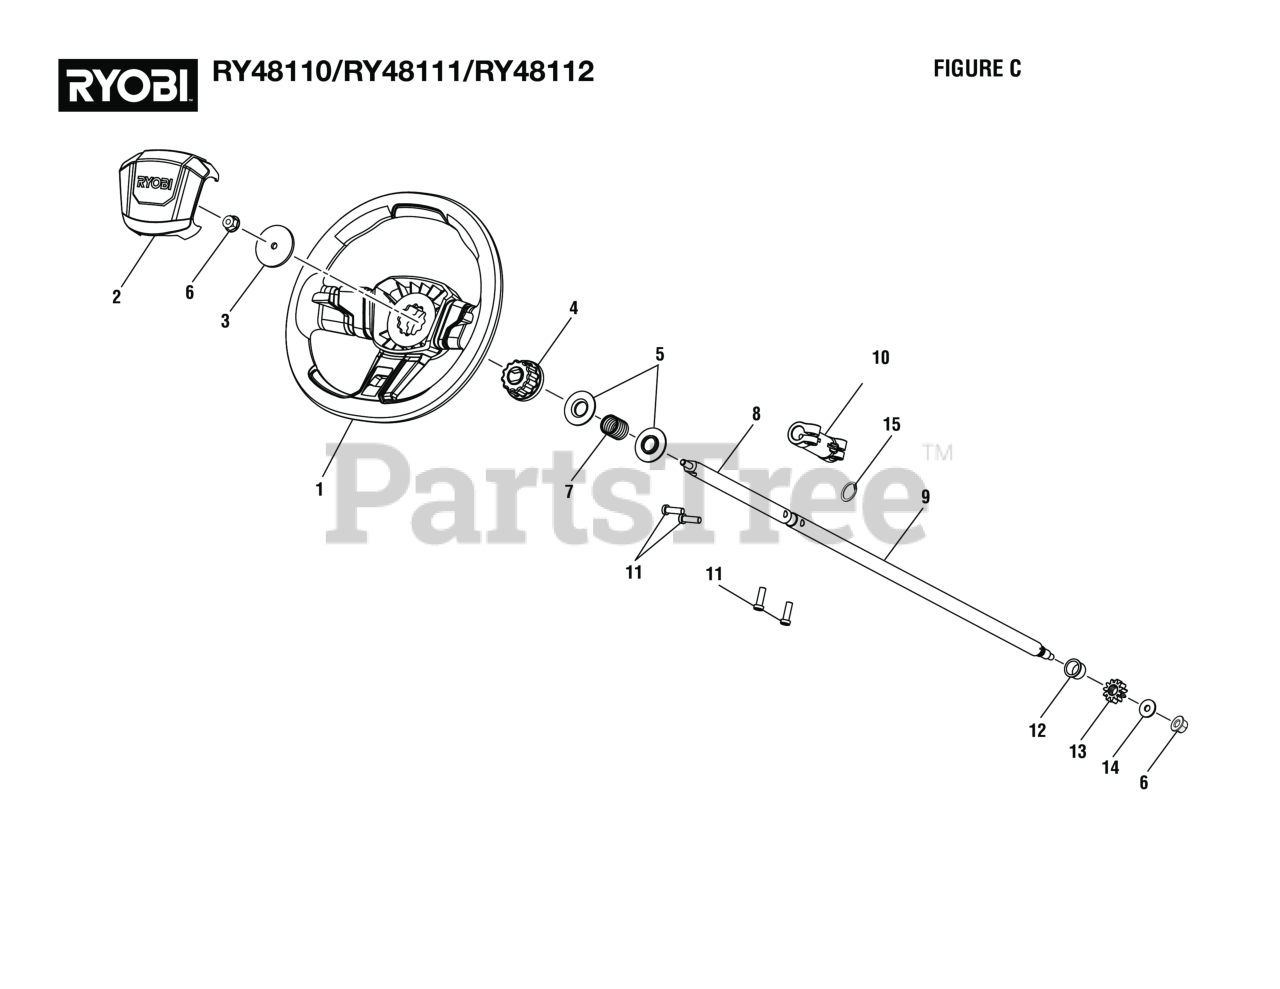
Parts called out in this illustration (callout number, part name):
1	Steering Wheel
2	Steering Wheel Cap
3	Washer Plate
4	Spline Collar
5	Spring Seat
6	Flange Nut (M8) (For Drive Motor Controller V)
7	Steering Shaft Spring
8	Upper Steering Shaft
9	Lower Steering Shaft
10	Steering Shaft Coupling
11	Screw (M8 x 25 mm, Soc. Hd.)
12	Flanged Bushing (19 x 22 x 15)
13	Steering Pinion Gear
14	Washer (OD 24 x ID8.4 x 2t)
15	Retaining Ring
